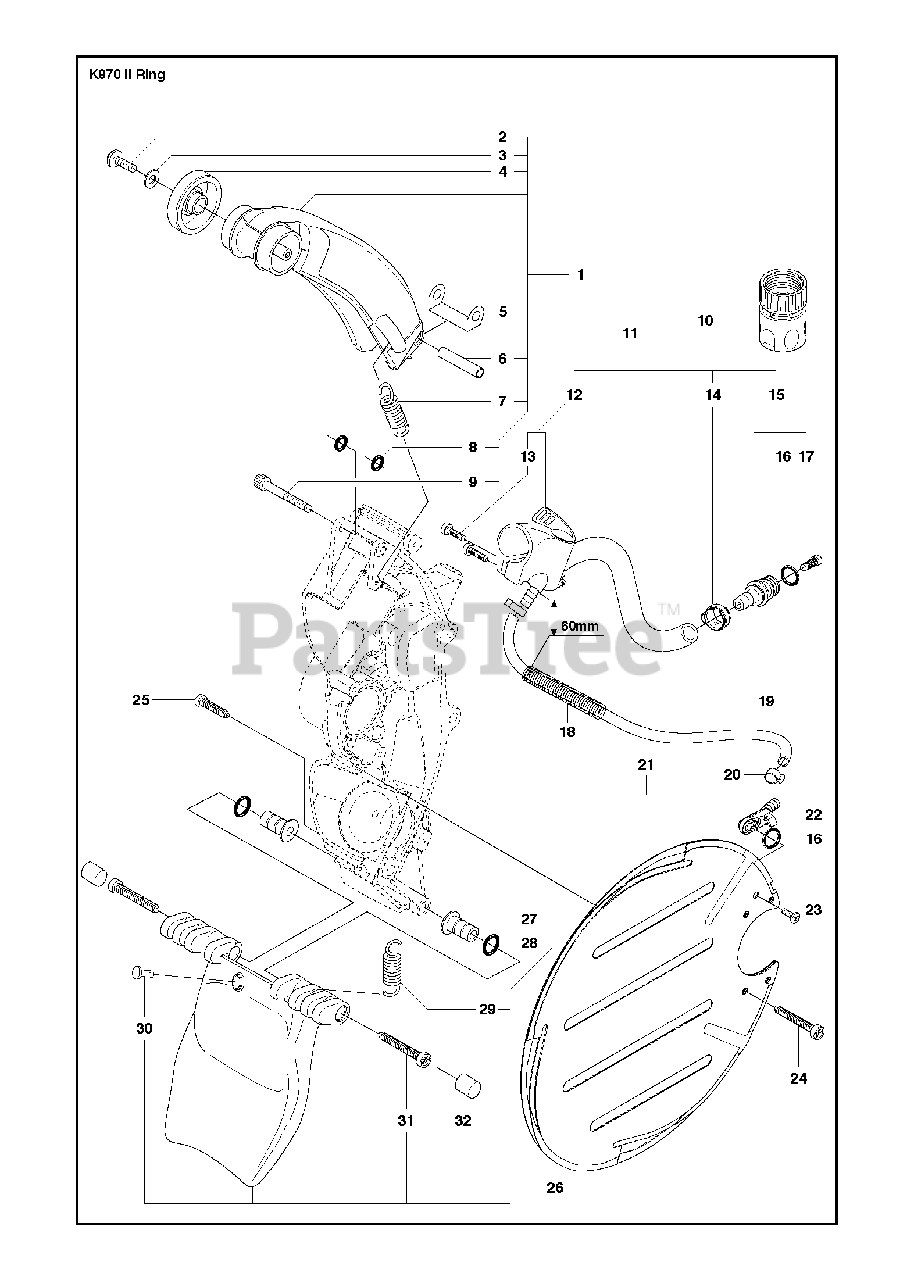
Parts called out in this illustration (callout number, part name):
1	BLADE GUARDIncl. 2 - 9
6	SPACING TUBE
9	SCREW ITXSCM
11	HOSE ASSYIncl. 12, 14 - 15
12	VALVE ASSYIncl 13
13	SCREW ITXSCT
14	HOSE CLAMP
15	NIPPLEIncl. 16, 17
16	O-RING
18	PROTECTIVE SPRING
20	HOSE CLAMP
23	SCREW CRPANT
25	SCREW ITXSCM
26	SPRAY GUARD ASSYIncl. 27 - 32
31	SCREW ITXSCM
